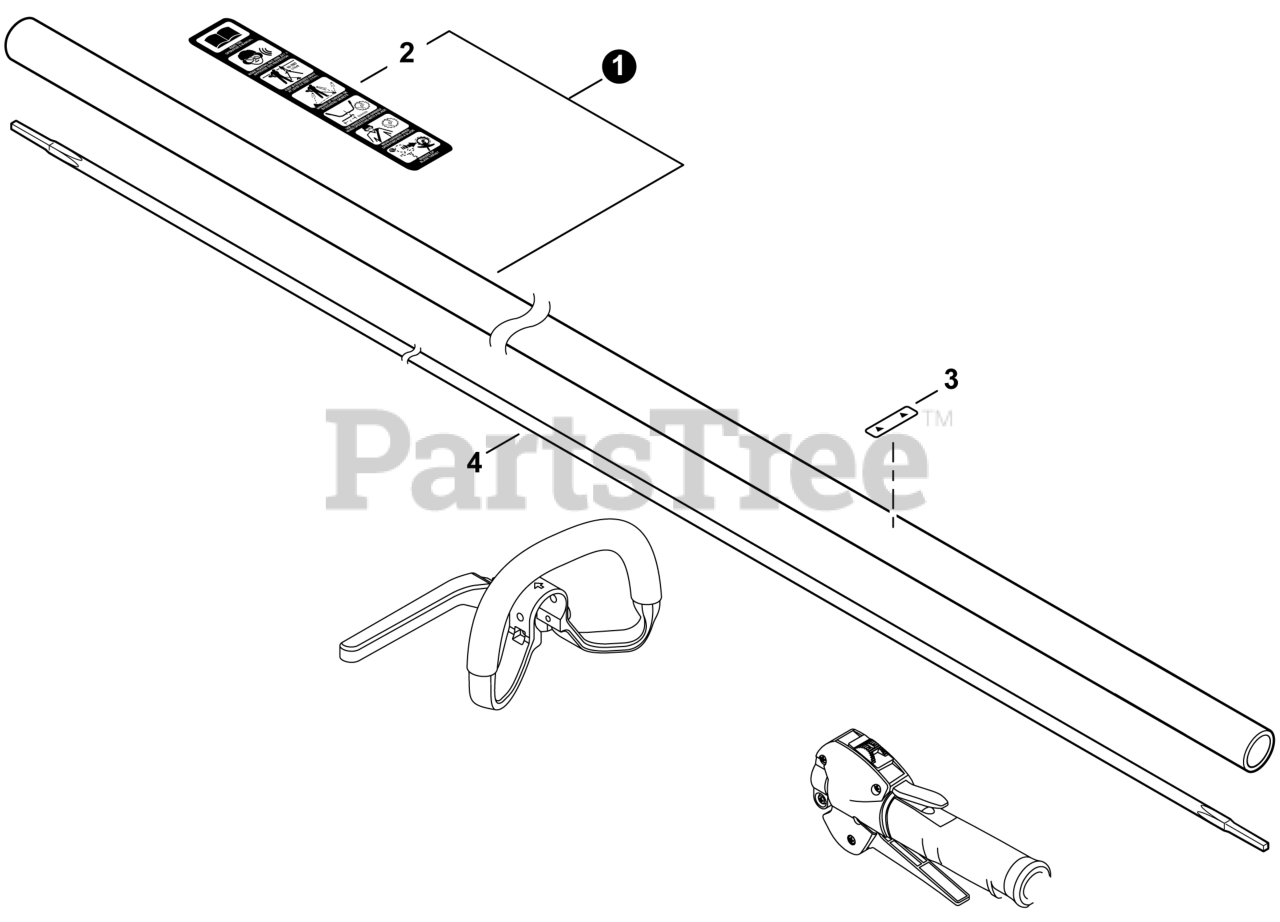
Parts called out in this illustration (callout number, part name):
1	MAIN PIPE ASSY
2	LABEL - CAUTION (BLADE CAPABLE)
3	LABEL - ALIGNMENT
4	DRIVESHAFT
